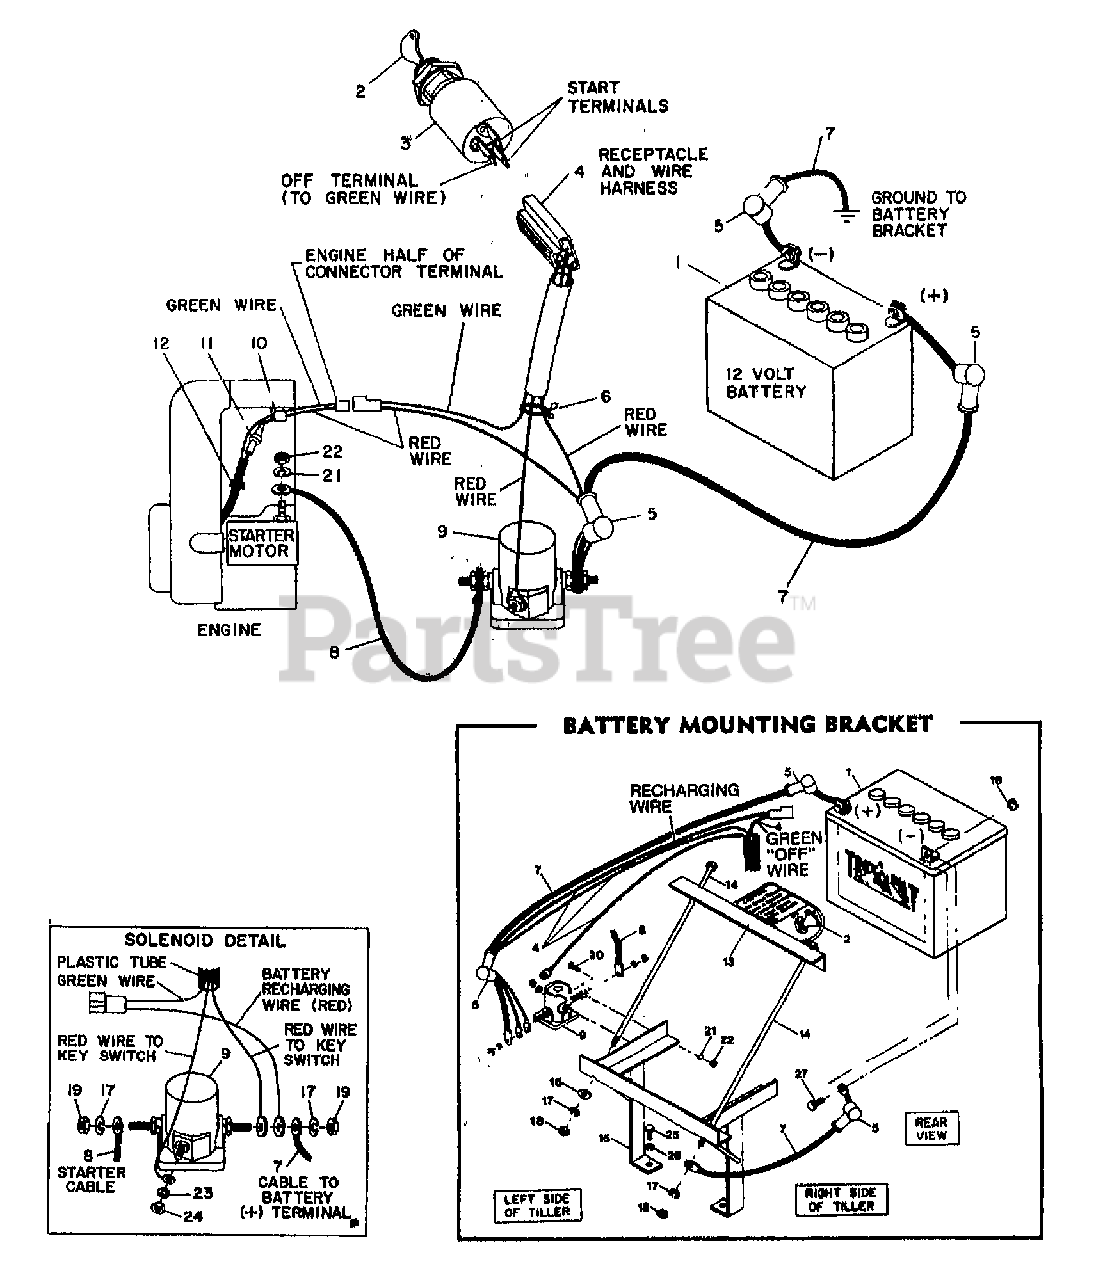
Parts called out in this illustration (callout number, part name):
1	KIT-VENTED BATTERY
2	KEYS(1 PAIR) FOR SWITCH
3	KEYSWITCH W/KEYS
4	HARNESS-WIRE 6HP
6	TIE-TWIST LOCK
7	CABLE-BATTERY
8	CABLE-BATTERY
9	KIT-SOL W/HDW
10	CLIP-SPECIAL
11	FUSE- 6AM, 3AGC
12	DIODE - BATTERY DISCHARGING
13	KEYSWITCH PLATE/CLAMP-WELD
14	SCR-HH 5/16-18 X 9
15	KIT-BATTERY BRKT HORSE
16	WASHER-FLAT 5/16 SAE
17	WASHER-LK .312 ZP
18	NUT-HEX 5/16-18 ZP
19	NUT-HEX 5/16-24
20	SCR-RH 1/4-20 X .75 ZP
21	WASHER-LK .25 ZP
22	NUT-HEX 1/4-20 ZP
23	WASHER-EXTERNAL TOOTH 1
24	NUT-HH M10-32X.125
25	BOLT-HH 3/8-16X1.5 FTH ZP
26	WASHER-LK .375 @ DEPL
27	SCR-HHC 5/16-18X.75 GR 5 ZP
